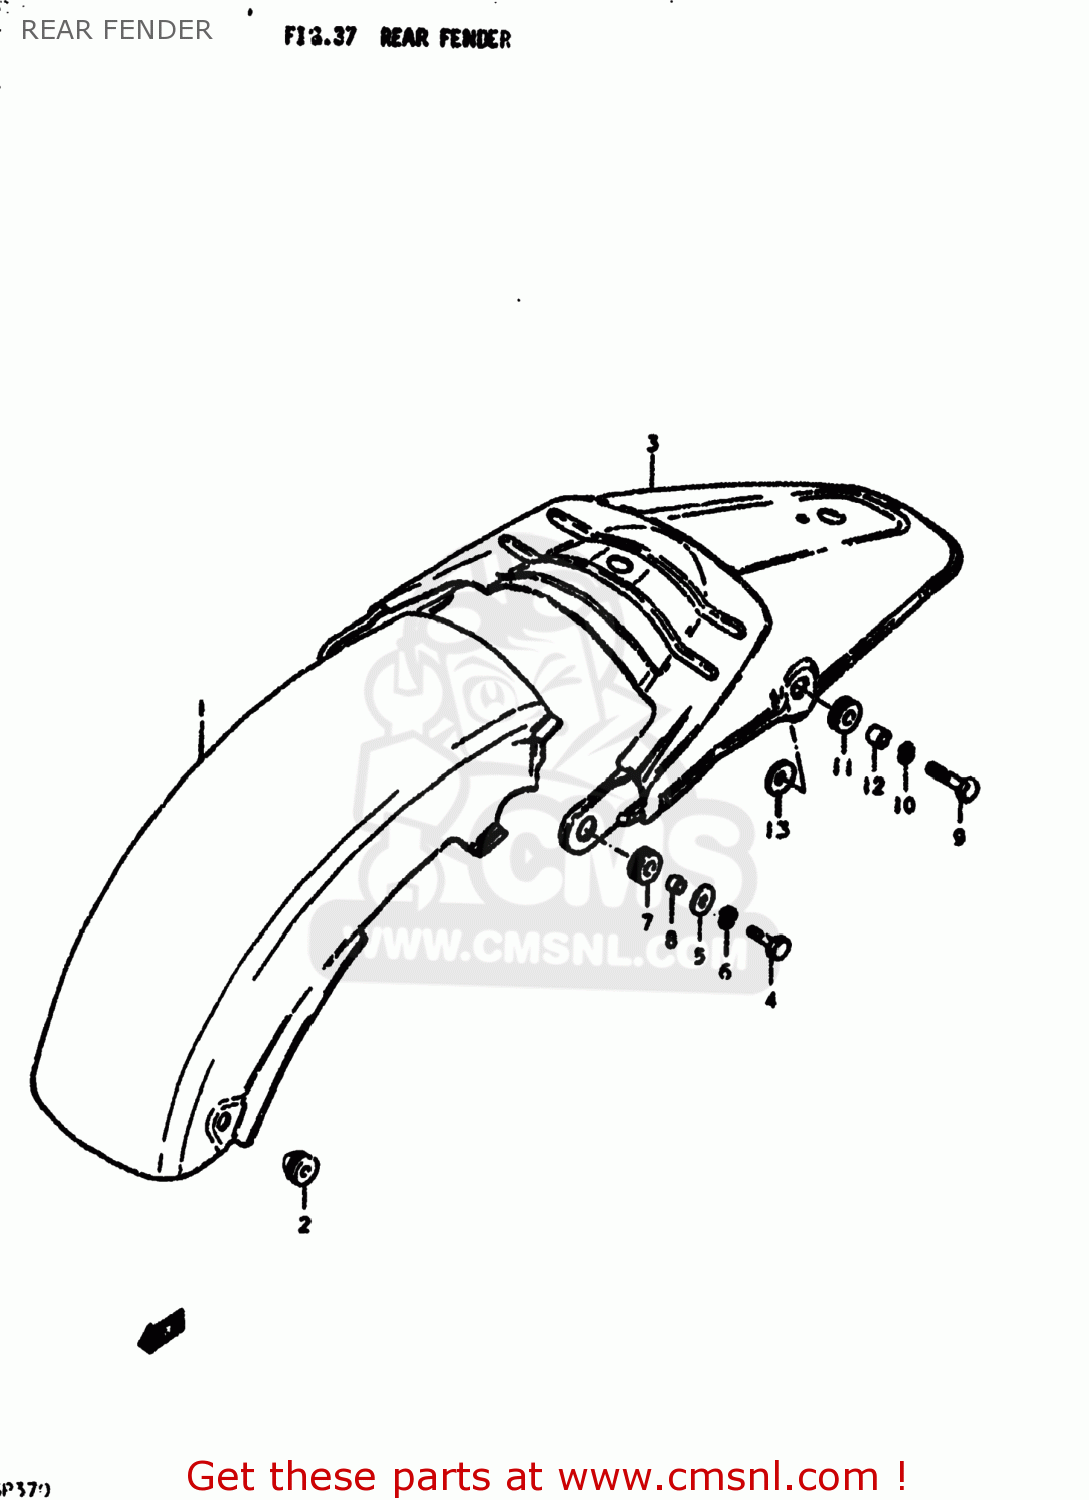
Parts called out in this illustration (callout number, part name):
1	FENDER,REAR
2	CUSHION,REAR FENDER
3	FENDER,REAR
4	BOLT
5	WASHER (6.5X20X1.2)
6	LOCK WASHER
7	CUSHION
8	SPACER(6.1X9X7.5)
9	BOLT
10	LOCK WASHER
11	CUSHION
12	SPACER(8.2X10X8)
13	WASHER (8.2X24X1.6)
